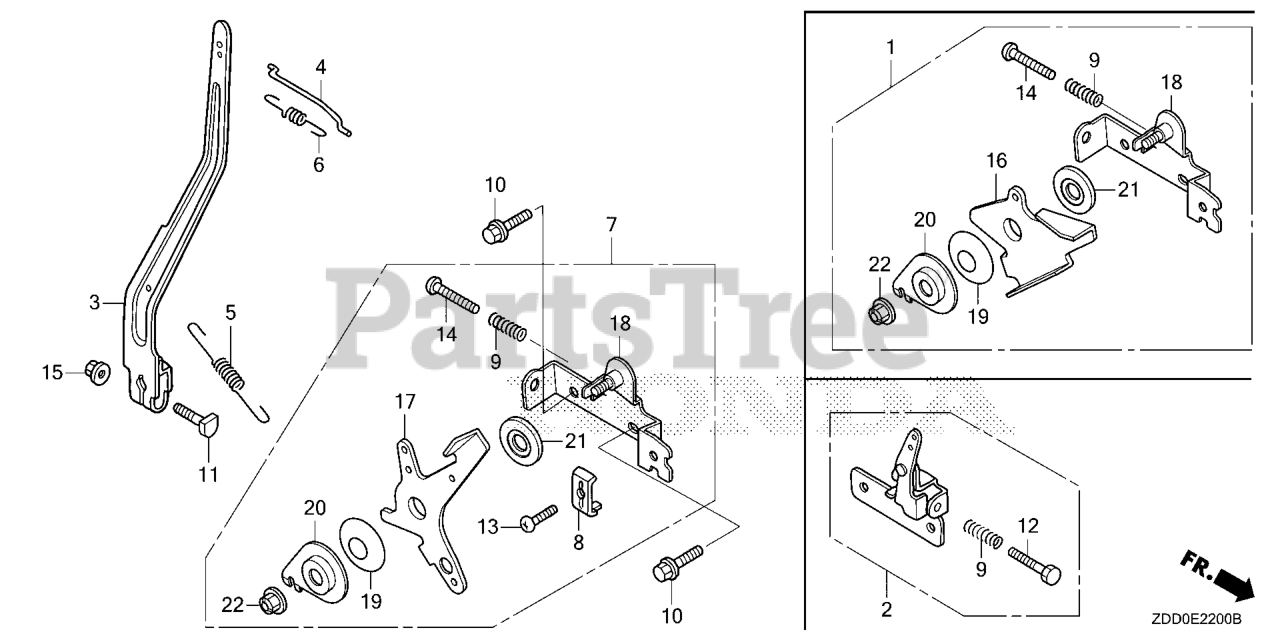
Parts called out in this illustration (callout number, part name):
1	CONTROL ASSY.
3	ARM, GOVERNOR
4	ROD, GOVERNOR
5	SPRING, GOVERNOR
6	SPRING, THROTTLE RETURN
9	SPRING, CONTROL ADJUSTING Use from Engine SN 2327377.
10	BOLT, FLANGE (6X14)
11	BOLT, GOVERNOR ARM
14	SCREW, PAN (5X25)
15	NUT, FLANGE (6MM)
